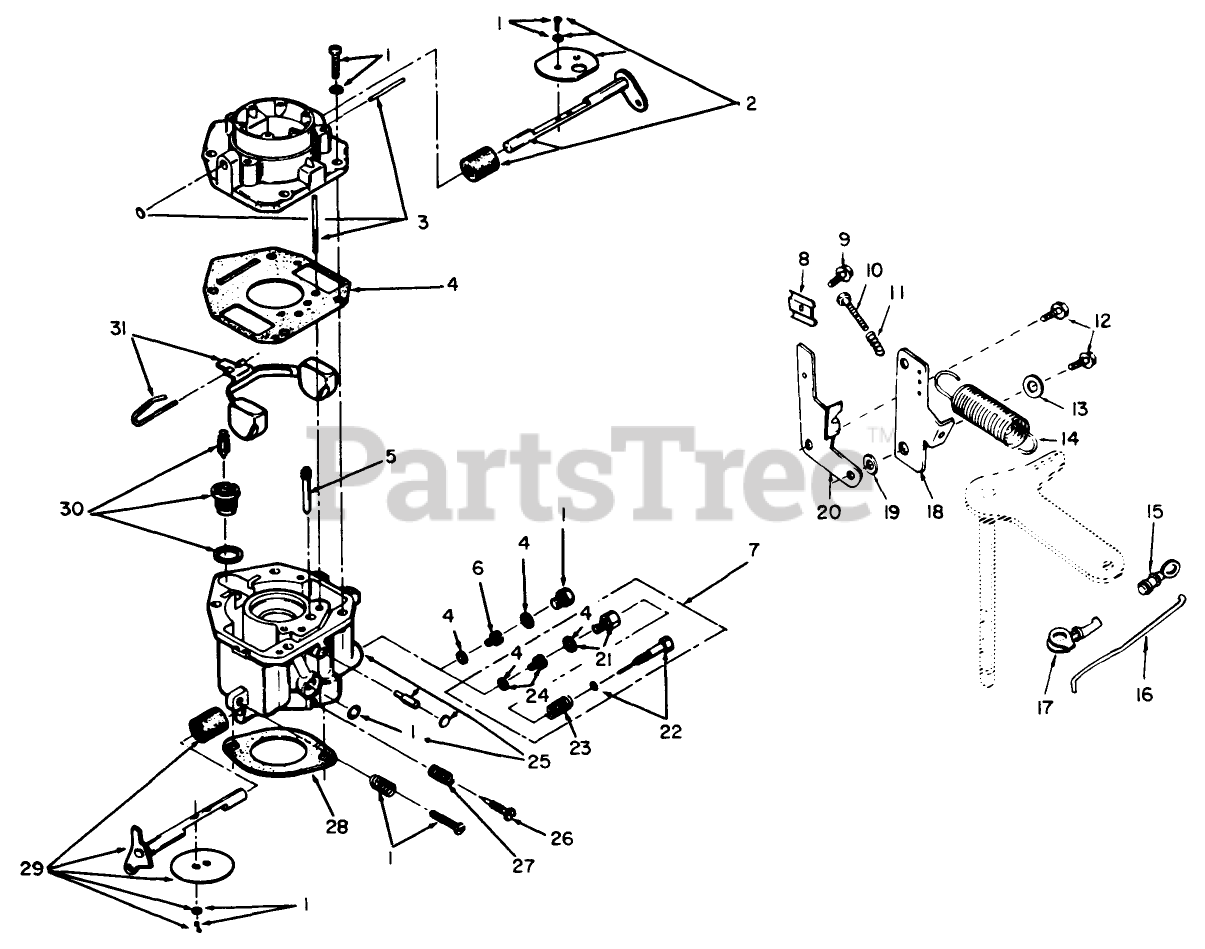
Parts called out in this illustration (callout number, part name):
1	SCREW & PLUG PKG
2	Choke, Shaft Kit
3	Intake, Air
4	GASKET PKG
5	IDLE JET
6	POWER JET
7	Kit-Variable Jet
9	TAPPING HEX HD CS
10	SCREW-TAP
11	SPRING
12	SCREW-HWH
13	FLAT WASHER
14	SPRING
16	CONTROL ROD
19	BUSHING
20	BRACKET-GOVERNOR
21	Retainer, Power Needle (Incl. Gasket)
22	NEEDLE
23	SPRING
24	PowerJet, Variable (Incl. Gasket)
26	IDLE ADJ SCREW NEEDLE
27	IDLE ADJ SPRING
28	Gasket
29	Throttle Shaft Kit
30	FLOAT VALVE
31	FLOAT
